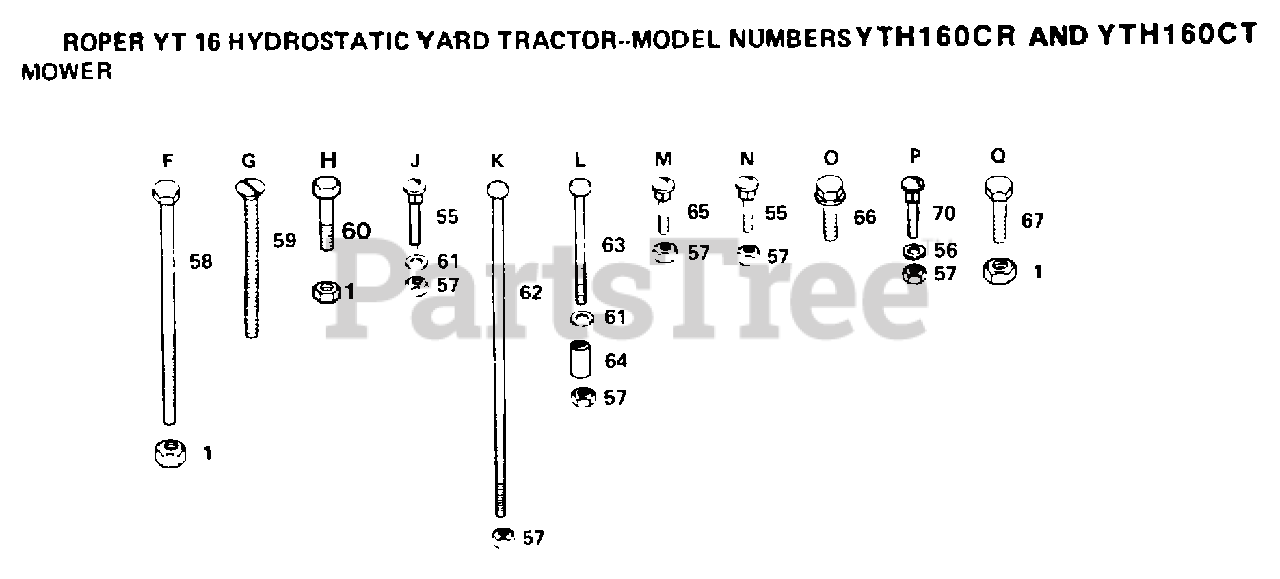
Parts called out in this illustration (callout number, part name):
55	BOLT
56	WASHER
58	BOLT - HEX 3/8 - 16 X 3
59	SCREW YT
61	WASHER M
62	BOLT
63	BOLT.HEX.5/16-1.5
64	SPLIT SPACER RT
65	BOLT
66	SCREW
67	BOLT
